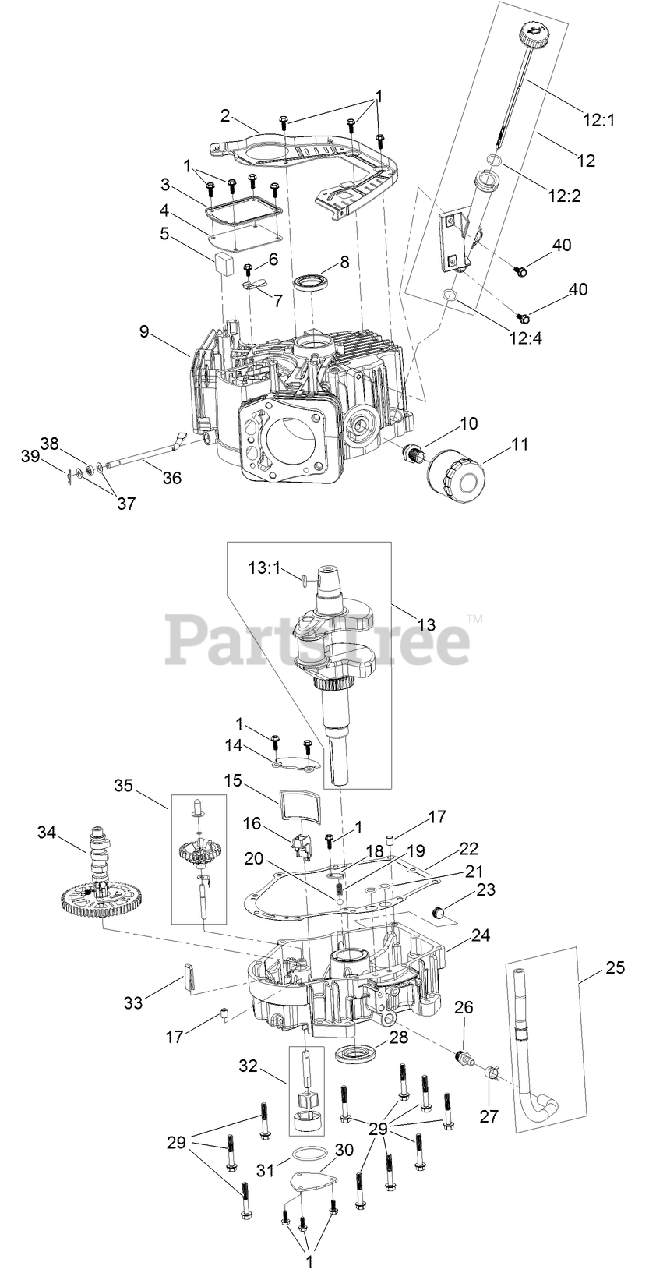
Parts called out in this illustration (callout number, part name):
1	SCREW-HHF
2	BAFFLE
3	COVER-BREATHER
4	GASKET-BREATHER
5	FILTER-BREATHER
6	SCREW-HHF
7	VALVE-BREATHER
8	SEAL-OIL
9	CRANKCASE
10	ADAPTOR-FILTER, OIL
12	OIL TUBE ASM
12:1	DIPSTICK
12:2	O-RING
12:4	O-RING
13	CRANKSHAFT
13:1	KEY-WOODRUFF
14	COVER-SCREEN, OIL
15	SCREEN-OIL
16	RETAINER-SCREEN
17	PIN-DOWEL
18	PLATE-RETAINER
19	SPRING
20	VALVE-BALL
21	O-RING
22	GASKET-COVER, CRANKCASE
23	PLUG-DRAIN
24	COVER-CRANKCASE
25	OIL DRAIN HOSE ASM
26	FITTING-HOSE
27	CLAMP-HOSE
29	SCREW-HHF
30	COVER-OIL PUMP
31	O-RING
32	OIL PUMP ASM
33	DEFLECTOR-OIL, RUBBER
34	CAMSHAFT
35	GOVERNOR ASM
36	SHAFT-GOVERNOR
37	WASHER-PLAIN
38	SEAL-OIL
39	PIN-HAIR
40	SCREW-HHF
